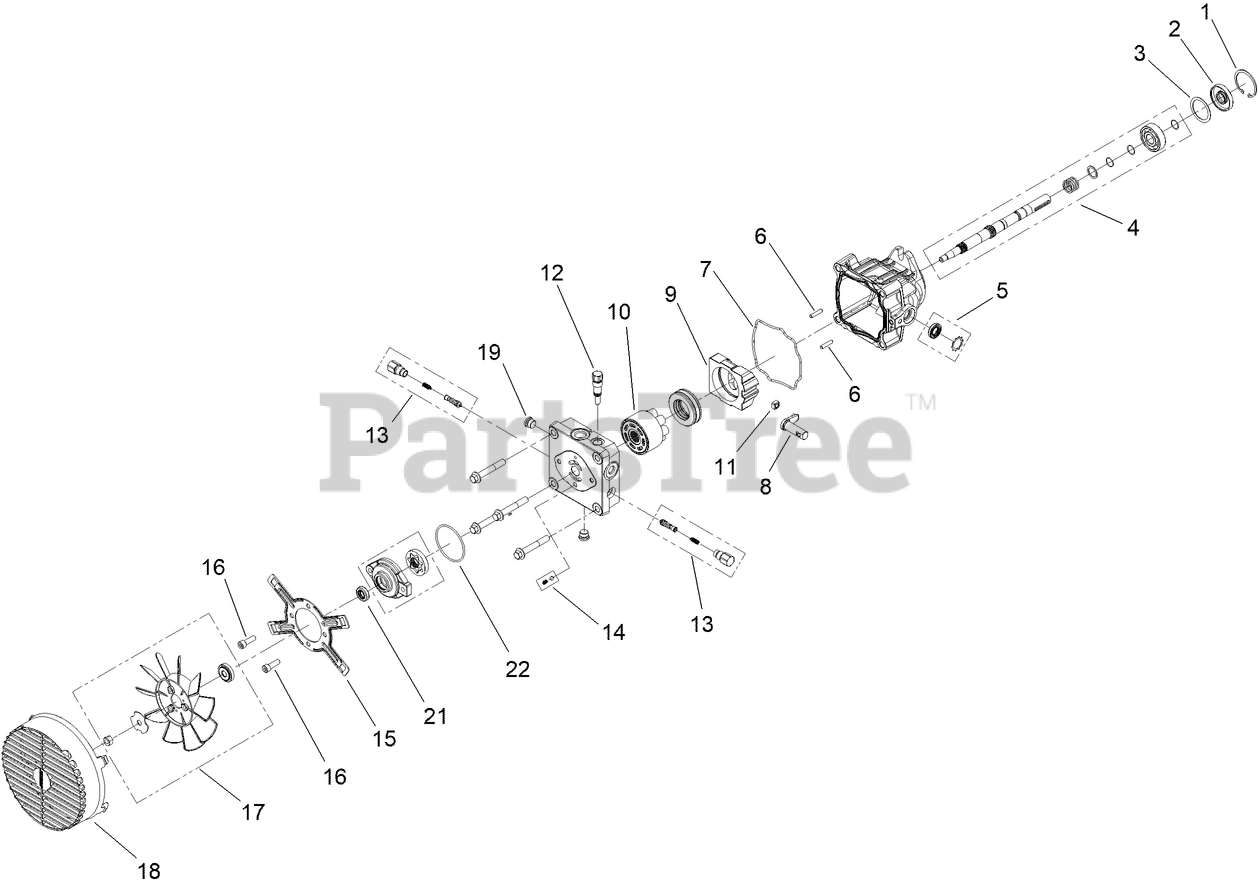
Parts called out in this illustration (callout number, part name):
1	RING-RETAINING
2	SEAL-LIP
3	WASHER-FLAT
4	Bearing, Input Shaft PR
5	TRUNNION SEAL KIT
6	PIN-HEADLESS, STRAIGHT
7	O-RING
8	ARM-TRUNNION
9	SWASHPLATE
10	CYLINDER BLOCK KIT
11	GUIDE-SLOT
12	BYPASS VALVE KIT
13	SHOCK VALVE KIT
14	CHARGE RELIEF KIT
15	BRACKET-FAN
17	FAN HUB KIT
18	GUARD-FAN, PUMP
19	PLUG-THREAD, STRAIGHT
21	SHAFT SEAL
22	0-RING SEAL
